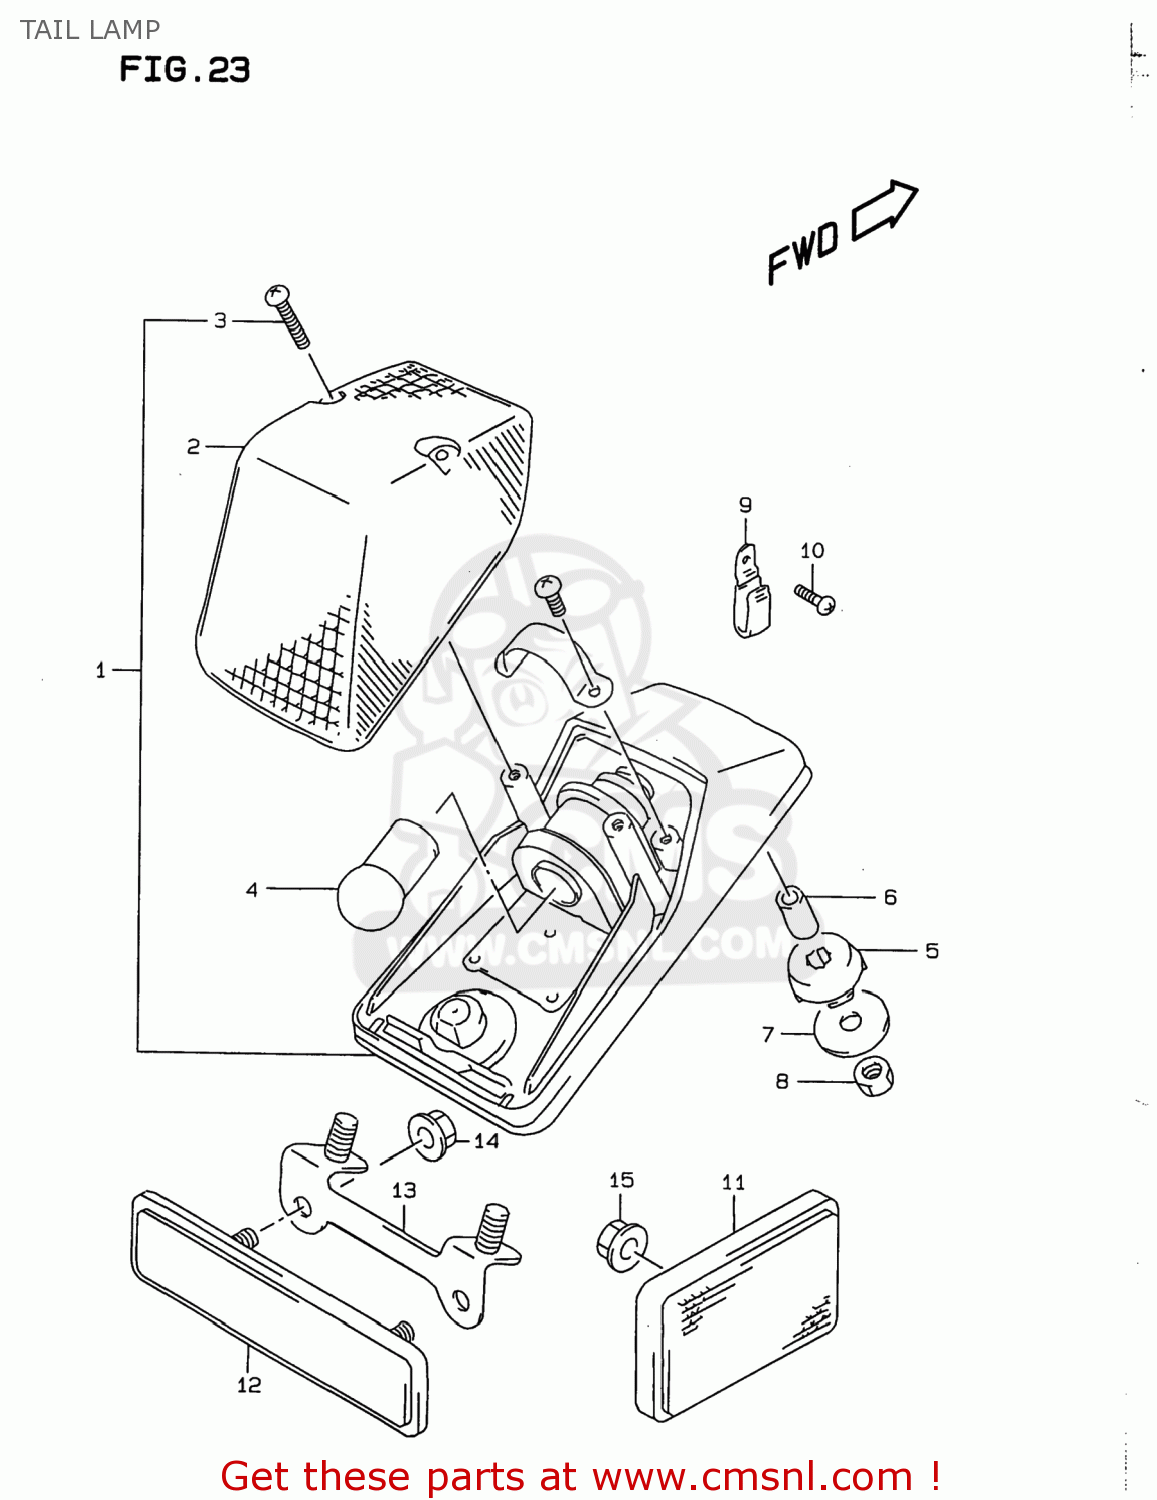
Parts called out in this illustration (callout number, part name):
1	LAMP ASSY,TAIL
2	LENS
3	SCREW
4	BULB(12V5W,BF150-40160A)
5	CUSHION
6	SPACER(6.4X9.2X12)
7	WASHER(6.5X20X1.2)
8	NUT 6MM
9	CLAMP
10	SCREW
11	REFLECTOR ASSY,RR SIDE
12	REFLEX REFLECTOR,RR
13	BRACKET,REAR REFLECTOR
14	NUT
15	NUT
